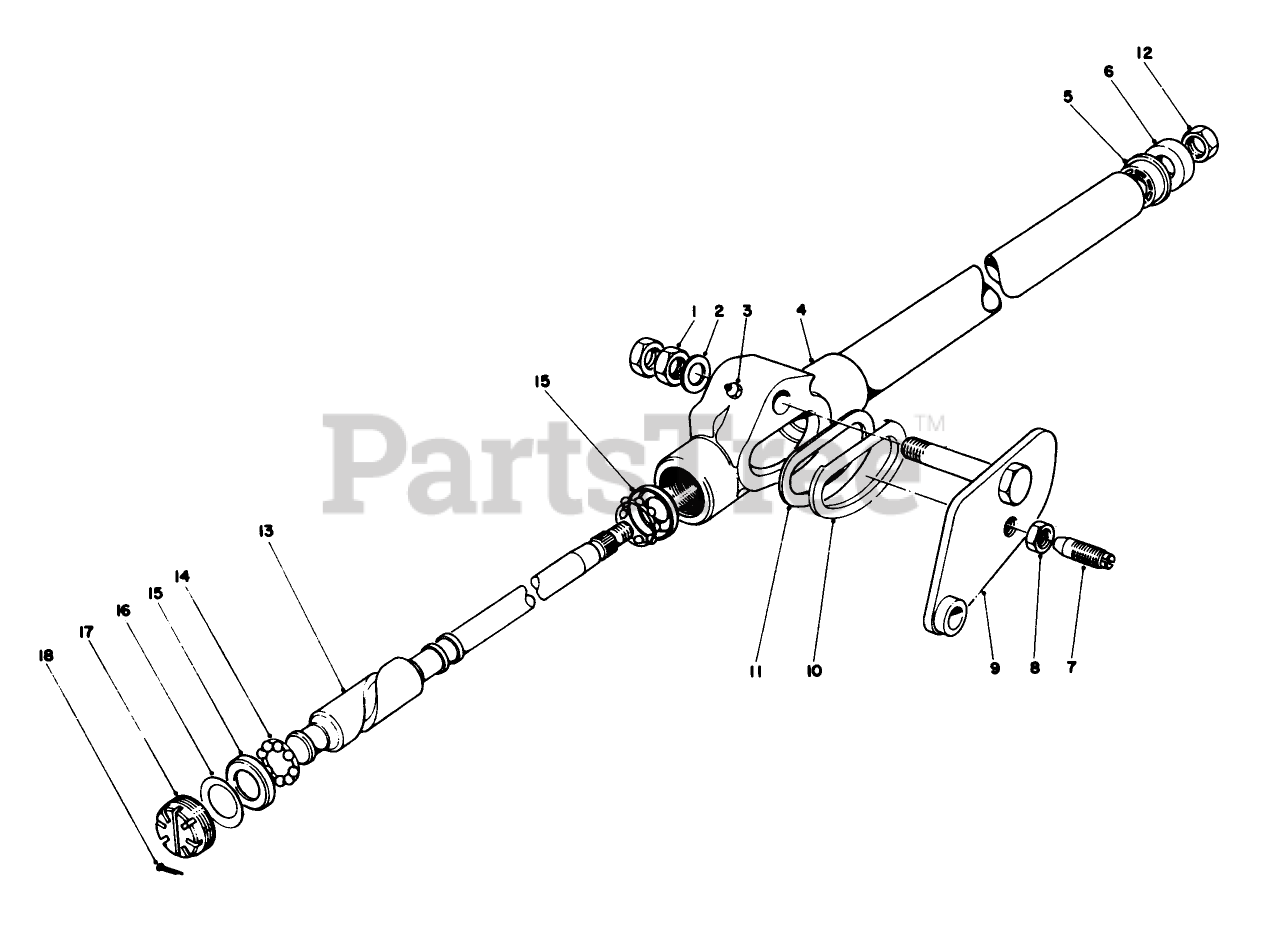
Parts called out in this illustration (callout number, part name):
1	NUT-JAM
2	Washer
3	ZERK FITTING
4	Inner Tunnel
5	BUSH & RETAINER ASM
6	COVER-DUST
7	LEVER STUD
8	NUT-HEX
9	LEVER & BOLT ASM
10	SEAL RETAINING
12	NUT-JAM
13	Cam & Tube Assembly
14	Retainer & Ball Assembly
15	BalI Cup
16	WASHER-BELLEVILLE
17	ADJUSTING PLUG
18	PIN-COTTER
